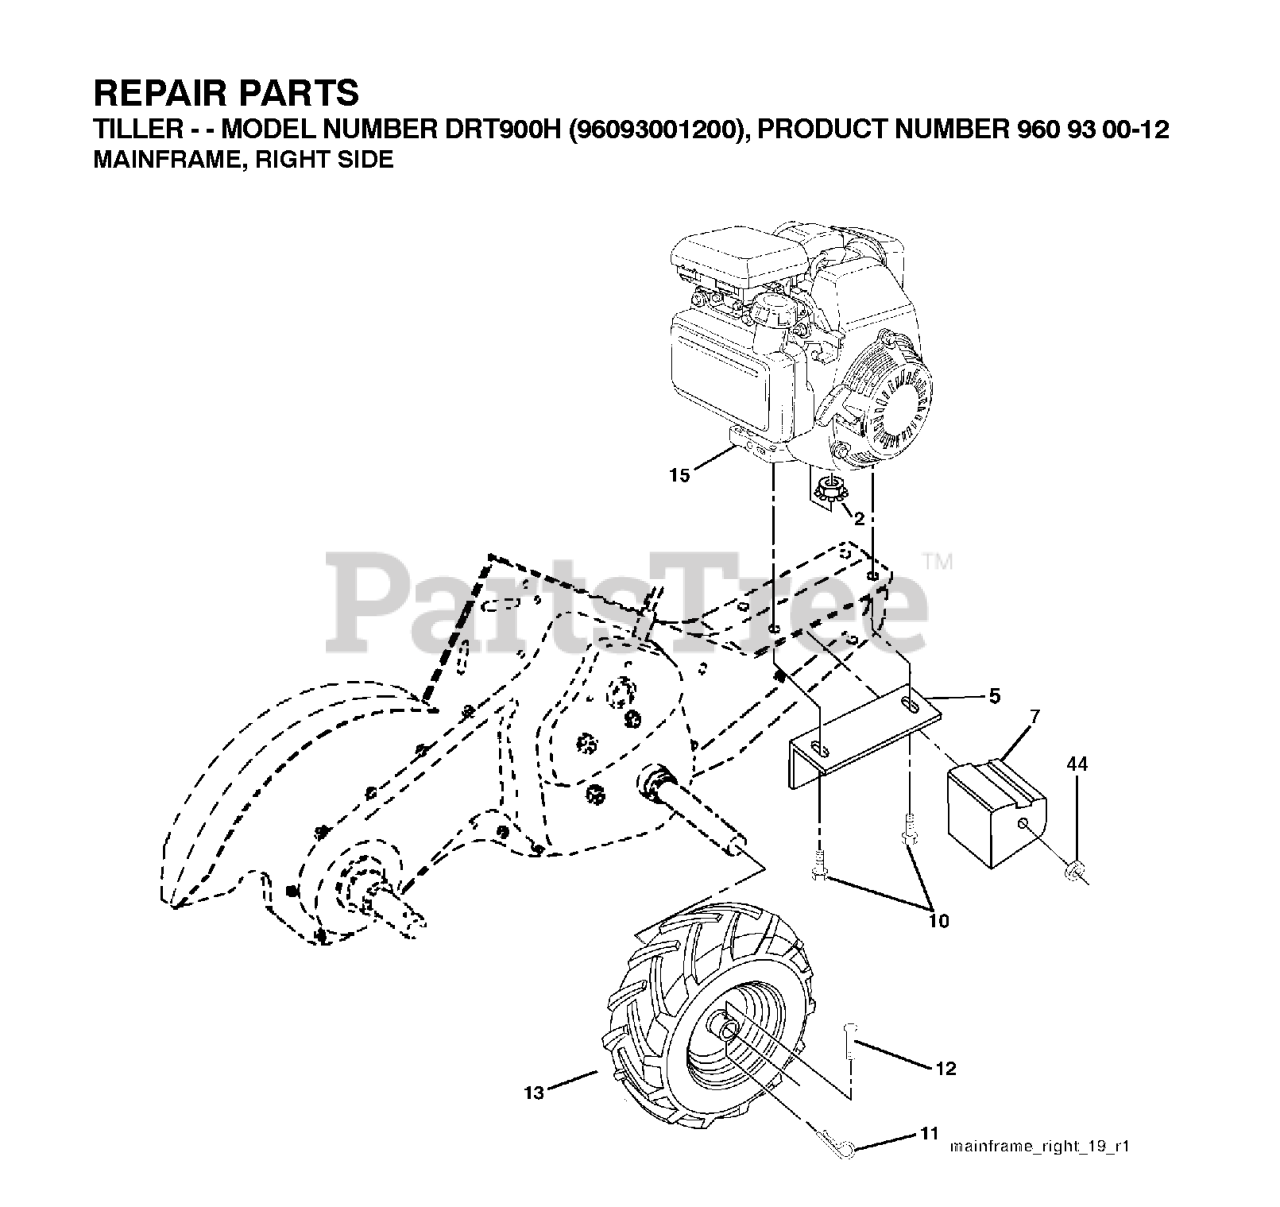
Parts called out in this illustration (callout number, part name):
2	LOCKNUT-FLANGE 5/16-18
5	DNO BRACKET RH CRT
7	COUNTERWEIGHT, RH
10	BOLT
11	RETAINER M
12	RIVET,DRILLED
13	TIRE.13X5-6.CHEVRON.TILLER
